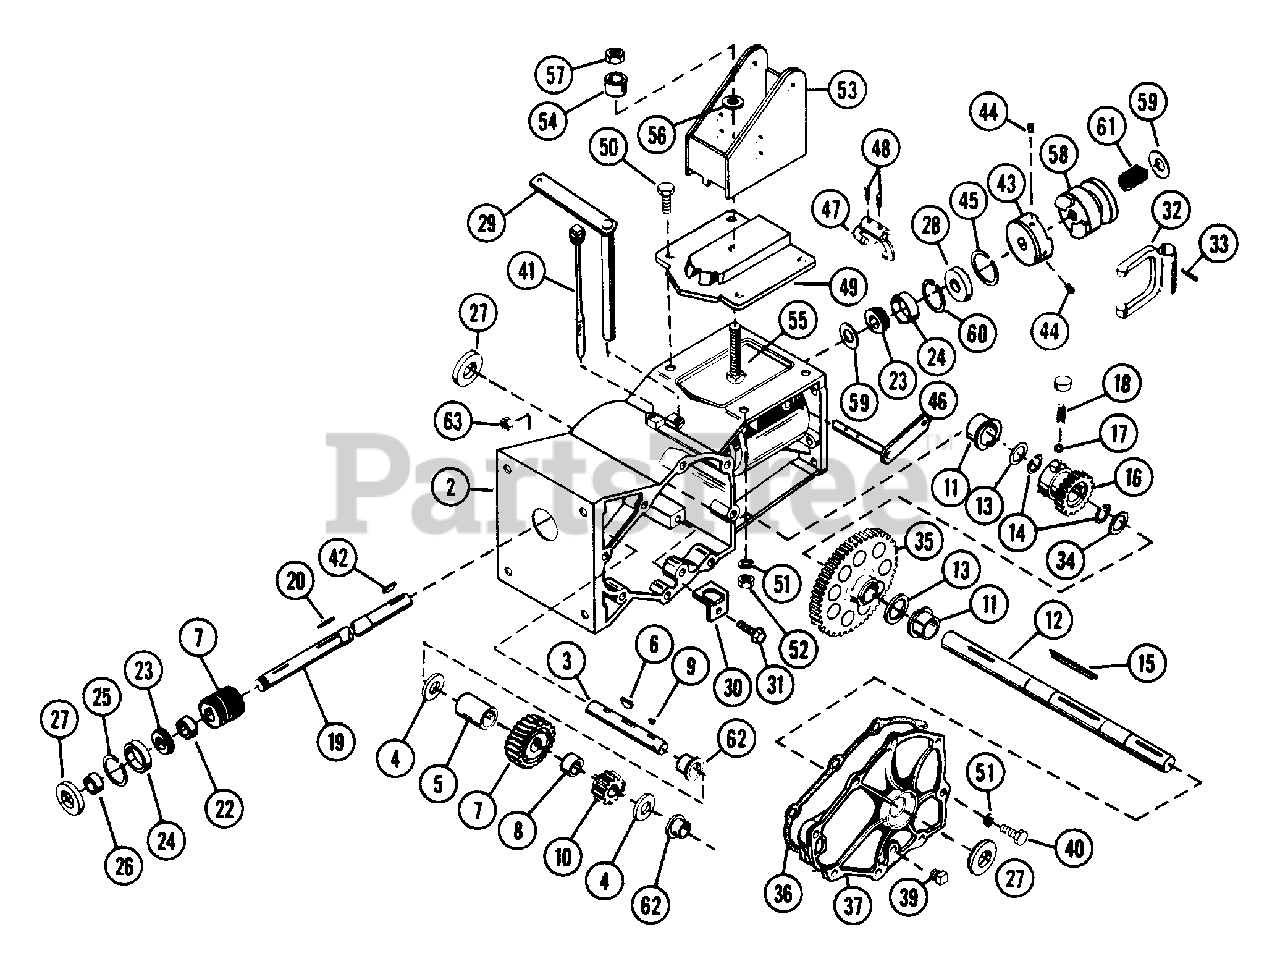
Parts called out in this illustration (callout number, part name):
1	TRANSMISSION GEARCASE ASSEMBLY
2	TRANSMISSION HOUSING
3	PINION SHAFT
4	WSHR-HDND-THRST .758X1.23X.031
5	SPACER 1.13 X .75 X 1.64
6	KEY-WDRF .25X.687X.375
7	WORM AND WORM GEAR
8	SPACER 1.25 X .75 X .75
9	KEY-WDRF .188X.75X.313 SAE 9
10	LOW PINION
11	BSHG-FLG 1.000X1.25X1.000X1.50
12	AXLE SHAFT
13	WSHR-HRD-THRS 1.007X1.542X.062
14	RG-RTNG-EXT 1.00X.078
15	KEY-FTHR .25X2.75X.25 SAE1035
16	CLUTCH HUB
17	STEEL BALL
18	SG-COMP .047X.31X.593 WLD11
19	WORM SHAFT
20	KEY-SQ .188X1.0X.188 SAE 8630
22	BSHG, SPCR .755X1.12X.50 PM
23	BRG-CONE .750X.61
24	BRG-CUP 1.781X.475
25	SNAP RING KIT
26	SPACER BUSHING .99 X .75 X .50
27	SEAL 1.000X1.785X.250
28	SEAL .750X1.781X.250
29	HIGH-LOW SHIFT LEVER
30	RETAINER CLIP
31	SCR-FLG-WHZ 10-24X.75 PL
32	SHIFT YOKE
33	PIN-ROLL .250X1.00
35	LOW GEAR
37	TRANSMISSION COVER
39	PIPE PLUG
40	BLT-HEX .31-18X1.00 PL GR 2
41	DIP STICK
42	KEY-FTHR .188X1.25X.187 SAE
43	TILLER DRIVING JAW
44	SCR-SET .32-18X.38 SKHCUPNL OH
45	RG-RTNG-EXT .750X.078
46	TINE ENGAGING FORK SHAFT
47	CLUTCH FORK
48	PIN-ROLL .188X1.00
49	PIVOT CAP
50	BLT-HEX .31-18X1.00 PL GR 2
51	WSHR-LK .312X.097 PL HVY
52	NUT-HEX .312-18
53	HANDLE BRACKET
55	SWIVEL BOLT
56	WSHR-FL-STL .511X1.441X.125 PL
57	NUT-LK-CTR .50-13
58	TILLER JAW CLUTCH
59	WSHR-FL-STL .755X1.375X.125
60	RG-RTNG-INT 1.781X.052
61	SG-COMP .080X.97X2.18 WLD14
62	BSHG-FLG .750X1.000X.750X1.250
63	NUT-HEX .375-16
